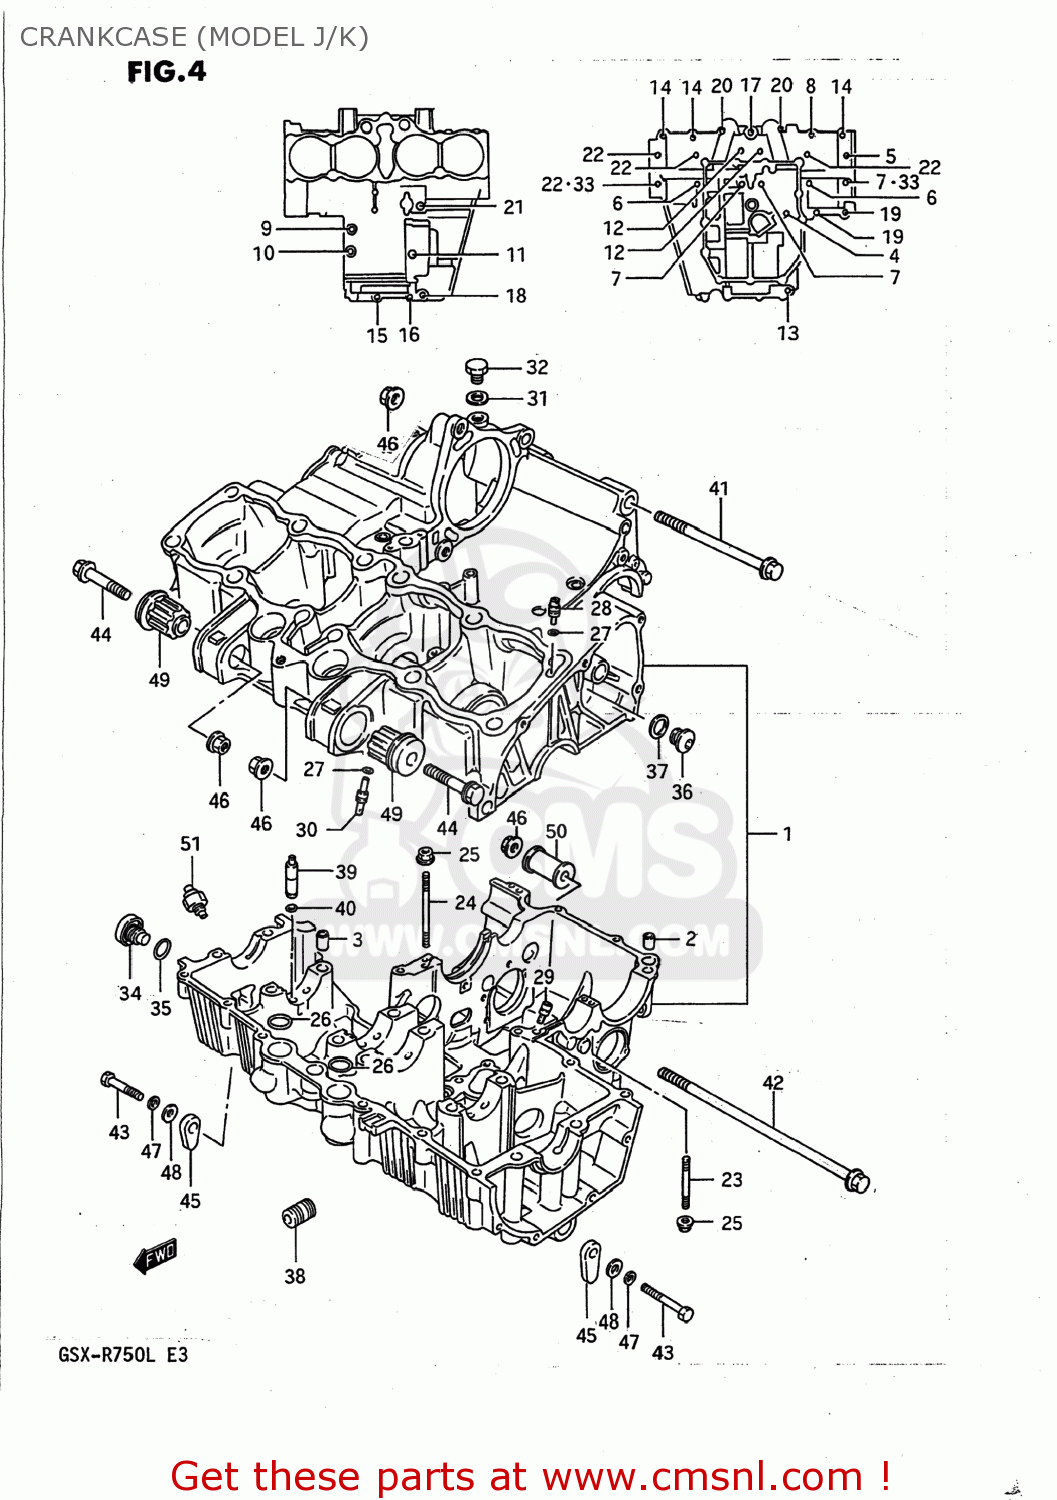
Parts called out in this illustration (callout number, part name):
1	CRANKCASE SET
2	PIN(10.4X13X22)
3	PIN (11X20)(SUS)
4	BOLT(6X105)
5	BOLT(8X105)
6	BOLT(8X125)
7	BOLT(8X115)
8	BOLT 6X35
9	BOLT
10	BOLT
11	BOLT
12	BOLT
13	BOLT 8X60
14	BOLT 6X35
15	BOLT
16	BOLT
17	BOLT 6X50
18	BOLT ,6X60
19	BOLT
20	BOLT
21	BOLT
22	BOLT(8X95)
23	STUD BOLT
24	STUD BOLT
25	NUT
26	O RING(D:2.5,ID:21)
27	O RING(D:1.2,ID:4)
28	JET,AIR
29	JET
30	JET,OIL GALLERY
31	GASKET(12.1X16.2X3.7) (NAS)
32	PLUG(12X9)
33	GASKET(8.5X17X2.3) (NAS)
34	PLUG
35	O RING(D:2.4,ID:16.8)
36	PLUG
37	GASKET(14X19.2X2) (NAS)
38	UNION,OIL STAND
39	VALVE ASSEMBLY,PISTON OIL
40	O RING(D:1.2,ID:4.7)
41	BOLT 10X150
42	BOLT(10X175)
43	BOLT 10X55
44	BOLT 10X55
45	NUT
46	NUT
47	WASHER,LOCK,10
48	WASHER
49	BUSH,ENGINE MOUNTING
50	SPACER,ENGINE MOUNT
51	SWITCH ASSEMBLY
